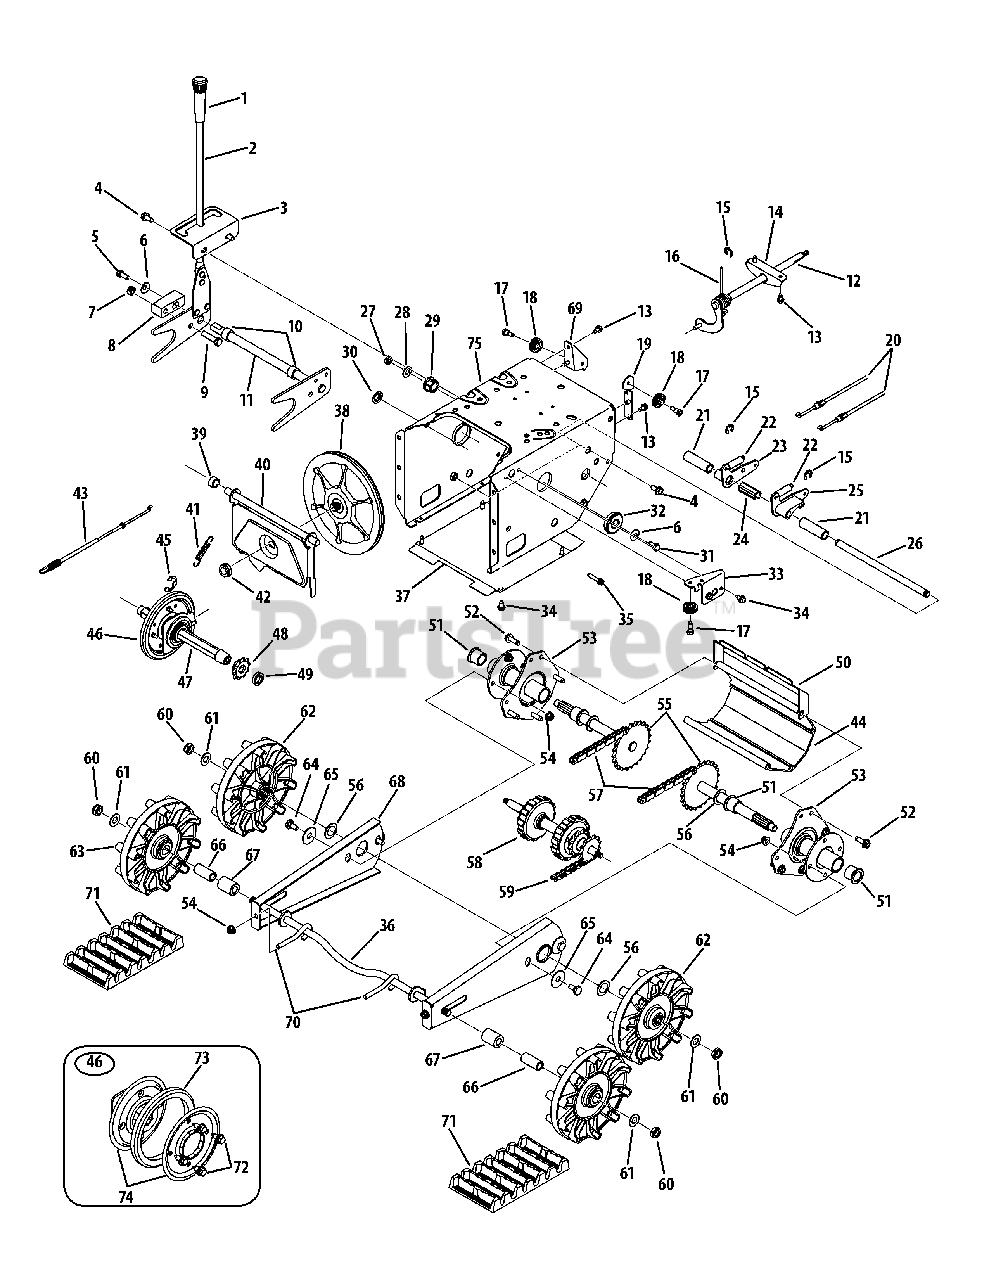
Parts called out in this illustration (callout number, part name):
1	Grip, .5 ID x 3.45
4	Hex Washer Screw, 5/16-18 x .750
5	Hex Screw, 5/16-24 x .75
6	Bell Washer, .340 x .872 x .060
7	Hex Lock Nut, 3/8-16
8	Lift Shaft Drive
9	Hex Screw, 3/8-16 x 1.50
10	Spacer, .828 ID x .875 OD x .500
12	Shift Rod Assembly
13	Hex Washer Screw, 1/4-20 x .500
16	Torsion Spring, .750 ID x .968
17	Shoulder Screw, .34 x .335 x 1/4-28
18	Cable Roller
19	Auger Cable Guide Bracket
20	Track Steering Cable
21	Spacer, .515 x 735 x 2.44
22	Extension Spring, .48 OD x 2.03
23	Dogg Assembly, RH
24	Spacer, .491 ID x 1.87
25	Dogg Assembly, LH
26	Shift Actuator
27	Jam Lock Nut, 3/8-24
28	Flat Washer, .406 x .875 x .059
29	Hex Flange Bearing
30	Speed Nut, .500
31	Hex Lock Screw, 5/16-18 x .625
32	Ball Bearing
33	Auger Cable Support Guide
34	Hex Washer Screw, 1/4-20 x .625
35	Hex Washer Screw, 1/4-20 x 1.000
37	Track Frame Cover
38	Friction Wheel Disc Assembly
39	Spacer, .525 ID x .750 x .42
40	Friction Wheel Support Bracket
41	Extension Spring
42	Flange Nut, 5/16-18
43	Drive Clutch Cable
46	Friction Wheel Assembly
47	Hex Track Shaft
48	Sprocket, 10T
49	Spacer, .675 ID x 1.00 OD x .23
50	Steering Cable Bracket
51	Flange Bearing
52	Hex Washer Screw, 5/16-18 x 1.0
53	Track Hub Assembly
54	Flange Lock Nut, 5/16-18
55	Track Axle Assembly
56	Flat Washer, .793 x 1.24 x .06
58	Drive Track Shift Assembly
60	Jam Lock Nut, 1/2-20
61	Flat Washer, .510 x 1.00 x .060
62	Track Drive Wheel
63	Track Idler Wheel
64	Shoulder Screw, .43 x .56 5/16-18
65	Flat Washer, .442 x 1.38 x .060
66	Spacer, .51 ID x .75 OD x 1.67
67	Spacer, .510 ID x 1.0 OD x 1.34
69	Drive Cable Guide Bracket
70	Eye Bolt, 5/16-18 x 3.0
71	Snow Trac
72	Hex Washer Screw, 1/4-14 x .625
73	Friction Wheel
74	Friction Plate
75	Frame Assembly
